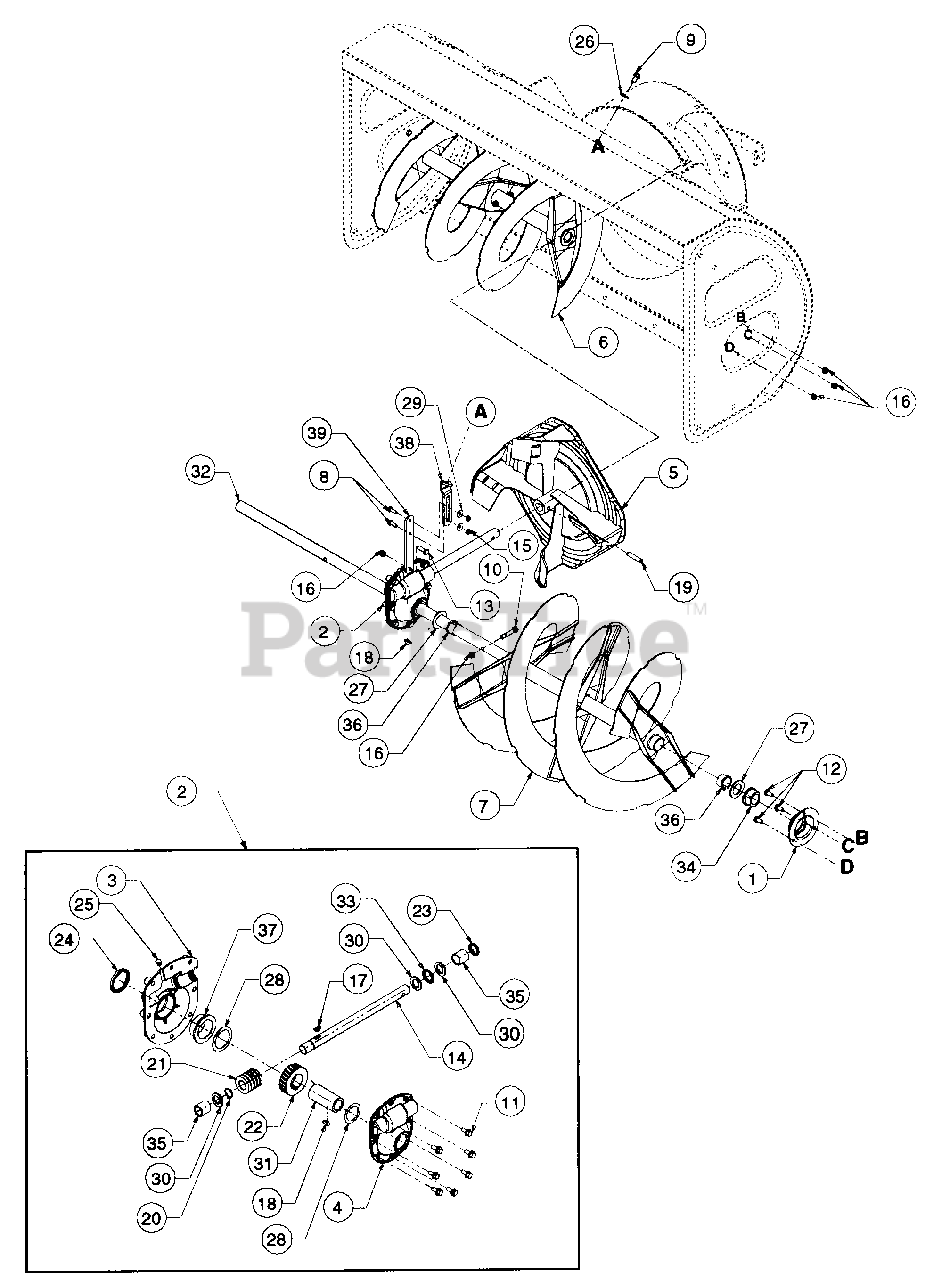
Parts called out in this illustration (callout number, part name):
2	Auger Gear Box Ass'y
3	Housing, Gear - RH
4	Housing, Gear - LH
8	Screw, Hex Cap, 1/4-28 X .75 GR5
9	Screw, Hex Wash. Hd. Tapp 5/16-12 X .75
10	Bolt, Shear, 5/16-18 X 1-3/4
11	Screw, Hex Wash. Hd. Tapp 5/16-18 X .75
12	Screw, Hex Cap, 5/16-18 X .625 GR5
13	Screw, Hex Cap, 5/16-18 X .875 GR5
14	Shaft, Input
15	Nut, Hex, 1/4-28
16	Nut, Hex Insert Lock, 5/16-18
17	Key, Hi Pro, 3/16 X 3/4
18	Key, Woodruff, 1/4 X 3/4 HDN
19	Pin, Spirol, 5/16 X 1.75
20	Ring, Snap
21	Gear, Worm
22	Gear, Worm
23	Seal, Oil
24	Seal, Oil
25	Plug, 1/4 X .437
26	Washer, Bell, .345 X .88 X .06 Thk
27	Washer, Flat, 1.0 X 1.75 X .1
28	Washer, Flat, 1.52 X 2.0 X .30
29	Washer, Bell, .265 X .75 X .062
30	Washer, Flat, .88 X 1.4 X .125
31	Shaft, Worm Gear
32	Shaft, Spiral Axle
33	Bearing, Thrust
34	Bearing, Flange w/Flats
35	Bearing, Sleeve
36	Bushing, Flange
37	Bearing, Flange
